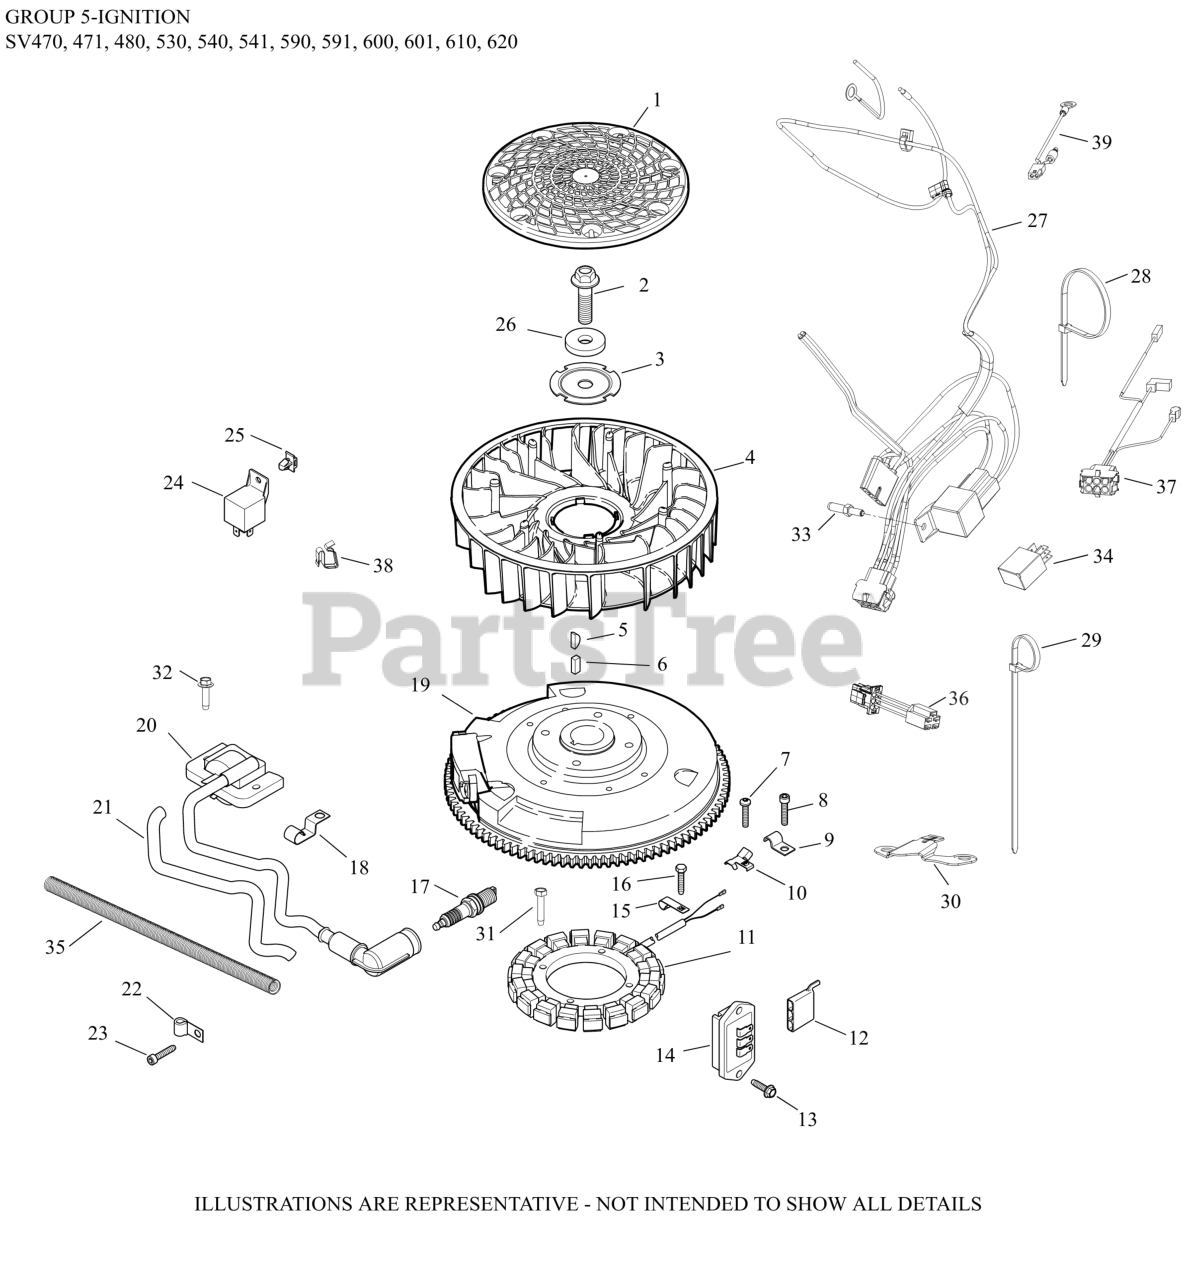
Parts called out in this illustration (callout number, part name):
1	SCREEN, GRASS
2	SCREW, HEX FLANGE
3	PLATE, FAN MOUNTING
6	KEY, SQUARE
11	KIT, 15 / 20 AMP STATOR
12	CONNECTOR
13	SCREW, FLG THD FRM M5X.8X20-(#25086399S)
14	REGULATOR/RECTIFIER-(#2540337S)
15	CLIP, WIRE
16	SCREW, M5X0.8X25 - (#25086402S)
17	PLUG, SPARK (STD)
19	FLYWHEEL - USE 20 025 46-S
20	MODULE, IGNITION-USE 20 584 03-S
26	WASHER, FLAT
27	HARNESS, WIRING
